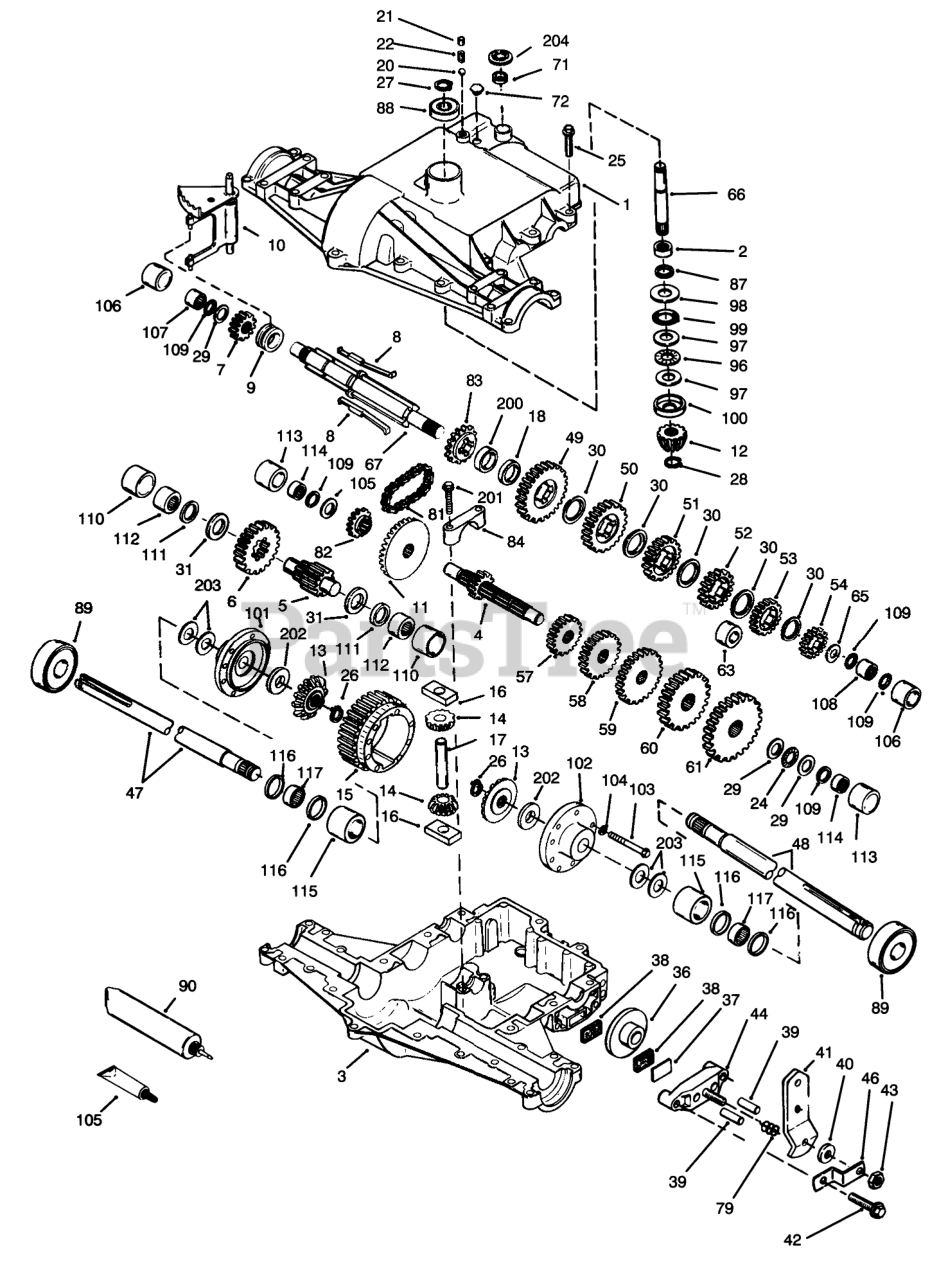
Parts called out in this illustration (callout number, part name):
1	Cover-Transaxle (Only On: 72042, 72062)
2	Bearing-Needle (Only On: 72042, 72062)
3	Case-Transaxle (Only On: 72042, 72062)
4	Countershaft-Gear 9t (Only On: 72042, 72062)
5	Shaft-Output (Only On: 72042, 72062)
6	Gear-Output 35t (Only On: 72042, 72062)
7	Gear-Spur 15t (Only On: 72042, 72062)
8	Key-Shift (Only On: 72042, 72062)
9	Collar-Shift (Only On: 72042, 72062)
10	Fork-Shift (Only On: 72042, 72062)
11	Gear-Bevel 33t (Only On: 72042, 72062)
12	Pinion-Input Bevel 13t (Only On: 72042, 72062)
13	Gear-Bevel 16t (Only On: 72042, 72062)
14	Pinion-Bevel 10t (Only On: 72042, 72062)
15	Gear-Ring (Only On: 72042, 72062)
16	Block-Drive (Only On: 72042, 72062)
17	Pin-Drive (Only On: 72042, 72062)
18	Spacer .350-.340 Thick (Only On: 72042, 72062)
20	Ball-Steel (Only On: 72042, 72062)
21	Screw-Set 3/8-16x3/8 (Only On: 72042, 72062)
22	Spring (Only On: 72042, 72062)
24	Bearing-Thrust (Only On: 72042, 72062)
25	Screw 5/16-18x1 1/4 (Only On: 72042, 72062)
26	Ring-Retaining (Only On: 72042, 72062)
27	Ring-Retaining (Only On: 72042, 72062)
28	Ring-Retaining (Only On: 72042, 72062)
29	Washer (Only On: 72042, 72062)
30	Washer (Only On: 72042, 72062)
31	Washer (Only On: 72042, 72062)
36	Disk-Brake (Only On: 72042, 72062)
37	Plate-Brake Pad (Only On: 72042, 72062)
38	Pad-Brake 2/Pkg (Only On: 72042, 72062)
39	Pin-Dowel (Only On: 72042, 72062)
40	Washer (Only On: 72042, 72062)
41	Lever-Brake (Only On: 72042, 72062)
42	Screw 1/4-20x1 1/4 (Only On: 72042, 72062)
43	Nut-Lock 5/16x24 (Only On: 72042, 72062)
44	Holder-Brake Pad (Only On: 72042, 72062)
46	Bracket-Brake Lever (Only On: 72042, 72062)
47	Axle 12 9/16" Long (Only On: 72042, 72062)
48	Axle 16 7/16" Long (Only On: 72042, 72062)
49	Gear-Spur 41t (Only On: 72042, 72062)
50	Gear-Spur 35t (Only On: 72042, 72062)
51	Gear-Spur 30t (Only On: 72042, 72062)
52	Gear Spur 25t (Only On: 72042, 72062)
53	Gear Spur 22t (Only On: 72042, 72062)
54	Gear Spur 19t (Only On: 72042, 72062)
57	Gear Spur 15t (Only On: 72042, 72062)
58	Gear Spur 20t (Only On: 72042, 72062)
59	Gear Spur 25t (Only On: 72042, 72062)
60	Gear Spur 28t (Only On: 72042, 72062)
61	Gear Spur 30t (Only On: 72042, 72062)
65	Washer (Only On: 72042, 72062)
66	Shaft-Input 30.910" Lg (Only On: 72042, 72062)
67	Shaft-Shifter/Brake (Only On: 72042, 72062)
71	Ring-Square Cut (Only On: 72042, 72062)
72	Plug-Threaded 9/16-18 (Only On: 72042, 72062)
79	Spring (Only On: 72042, 72062)
81	Chain-Roller #41 22" Lg (Only On: 72042, 72062)
82	Sprocket 10t (Only On: 72042, 72062)
83	Sprocket-Reverse 14t (Only On: 72042, 72062)
84	Cap-Bearing (Only On: 72042, 72062)
87	Seal-Oil 3/4" (Only On: 72042, 72062)
88	Bearing-Ball (Only On: 72042, 72062)
89	Bearing-Ball (Only On: 72042, 72062)
90	Grease 32 Oz Bentonite (Only On: 72042, 72062)
96	Bearing-Thrust (Only On: 72042, 72062)
97	Washer (Only On: 72042, 72062)
98	Washer (Only On: 72042, 72062)
99	O Ring (Only On: 72042, 72062)
100	Washer-Cupped (Only On: 72042, 72062)
101	Carrier-Differential (Only On: 72042, 72062)
102	Carrier-Differential (Only On: 72042, 72062)
103	Screw 14-20x2 1/4 (Only On: 72042, 72062)
104	Washer-Lock (Only On: 72042, 72062)
105	Washer (Only On: 72042, 72062)
106	Sleeve (Only On: 72042, 72062)
107	Bearing-Needle (Only On: 72042, 72062)
108	Bearing-Needle (Only On: 72042, 72062)
109	O Ring (Only On: 72042, 72062)
110	Sleeve (Only On: 72042, 72062)
111	Ring-Square Cut (Only On: 72042, 72062)
112	Bearing-Needle (Only On: 72042, 72062)
113	Sleeve (Only On: 72042, 72062)
114	Bearing-Needle (Only On: 72042, 72062)
115	Sleeve (Only On: 72042, 72062)
116	Ring-Square Cut (Only On: 72042, 72062)
117	Bearing-Needle (Only On: 72042, 72062)
150	Gasket Loctite #515 (Only On: 72042, 72062)
200	Spacer .276-.268 Thick (Only On: 72042, 72062)
201	Screw 1/4-20x1 1/4 (Only On: 72042, 72062)
202	Washer (Only On: 72042, 72062)
203	Washer (Only On: 72042, 72062)
204	Nut-Push (Only On: 72042, 72062)
